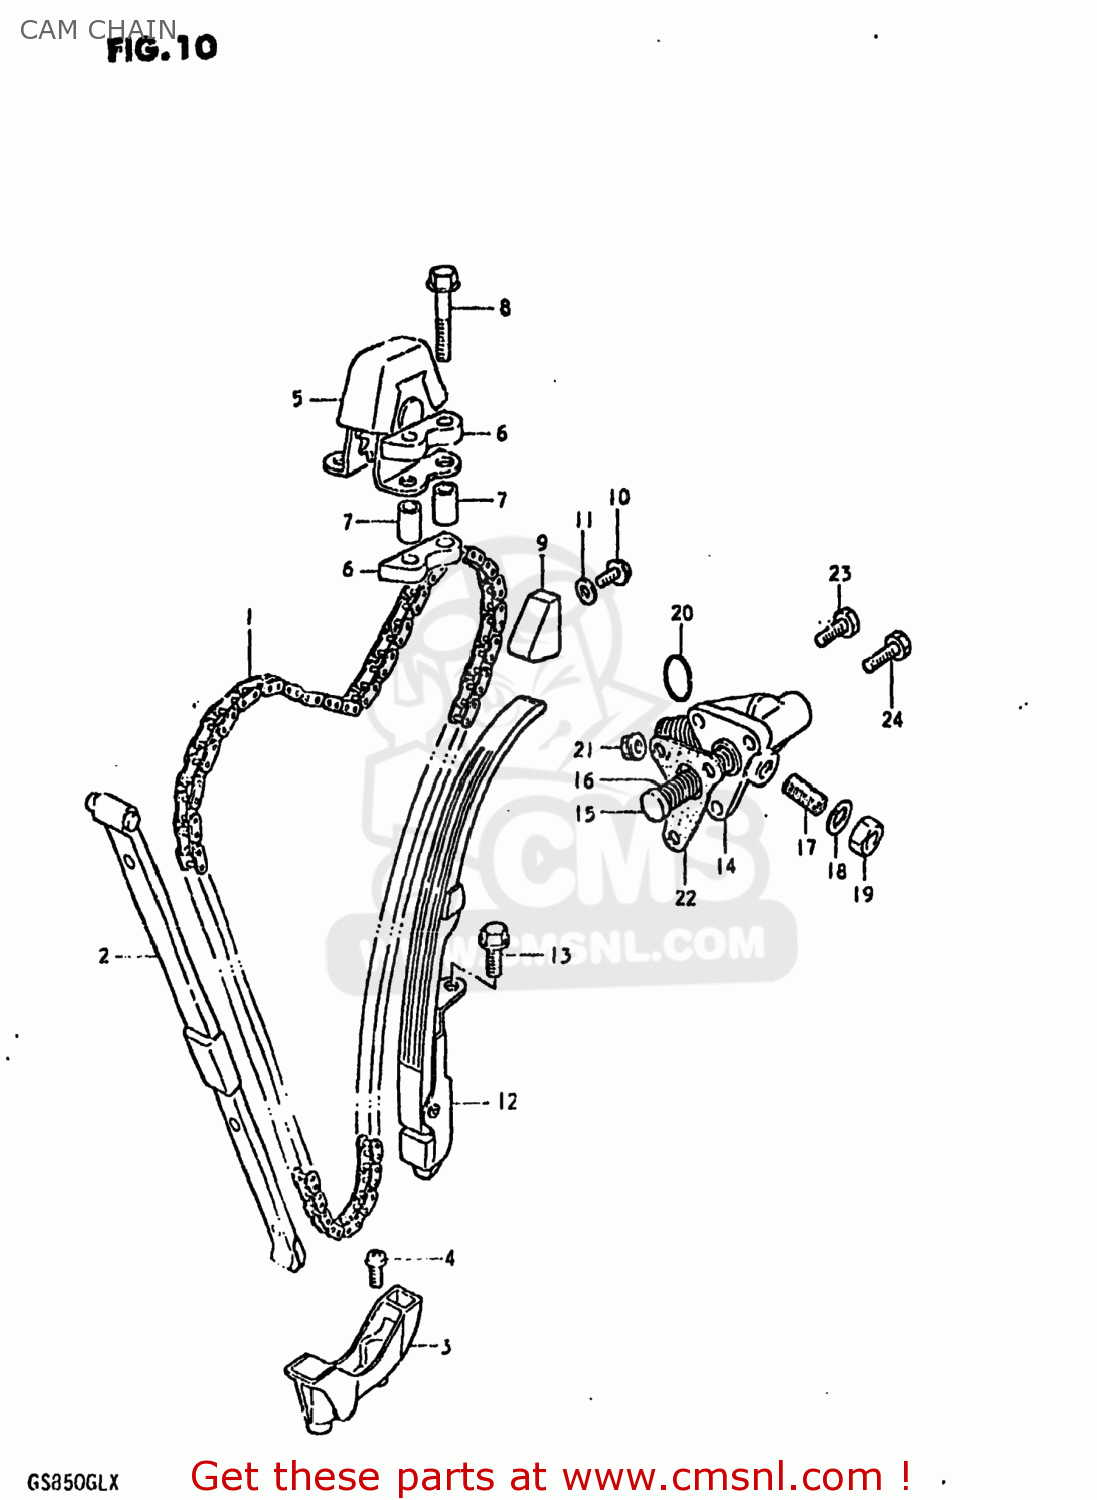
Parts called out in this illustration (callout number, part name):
1	CHAIN,CAMSHAFT DRIVE(120L)
2	GUIDE,CAM CHAIN NO.1
3	HOLDER,CAM CHAIN GUIDE
4	SCREW
5	IDLER,CAM CHAIN
6	CUSHION,IDLER
7	SPACER
8	BOLT
9	GUIDE,CAM CHAIN
10	BOLT
11	GASKET (NAS)
12	TENSIONER,CAM CHAIN
13	BOLT
14	ADJUSTER ASSEMBLY,TENSIONER
15	ROD,PUSH
16	SPRING
17	SCREW
18	WASHER
19	NUT
20	O-RING
21	NUT
22	GASKET,TENSIONER ADJUSTER (MCA)
23	SCREW (6X25)
24	SCREW
